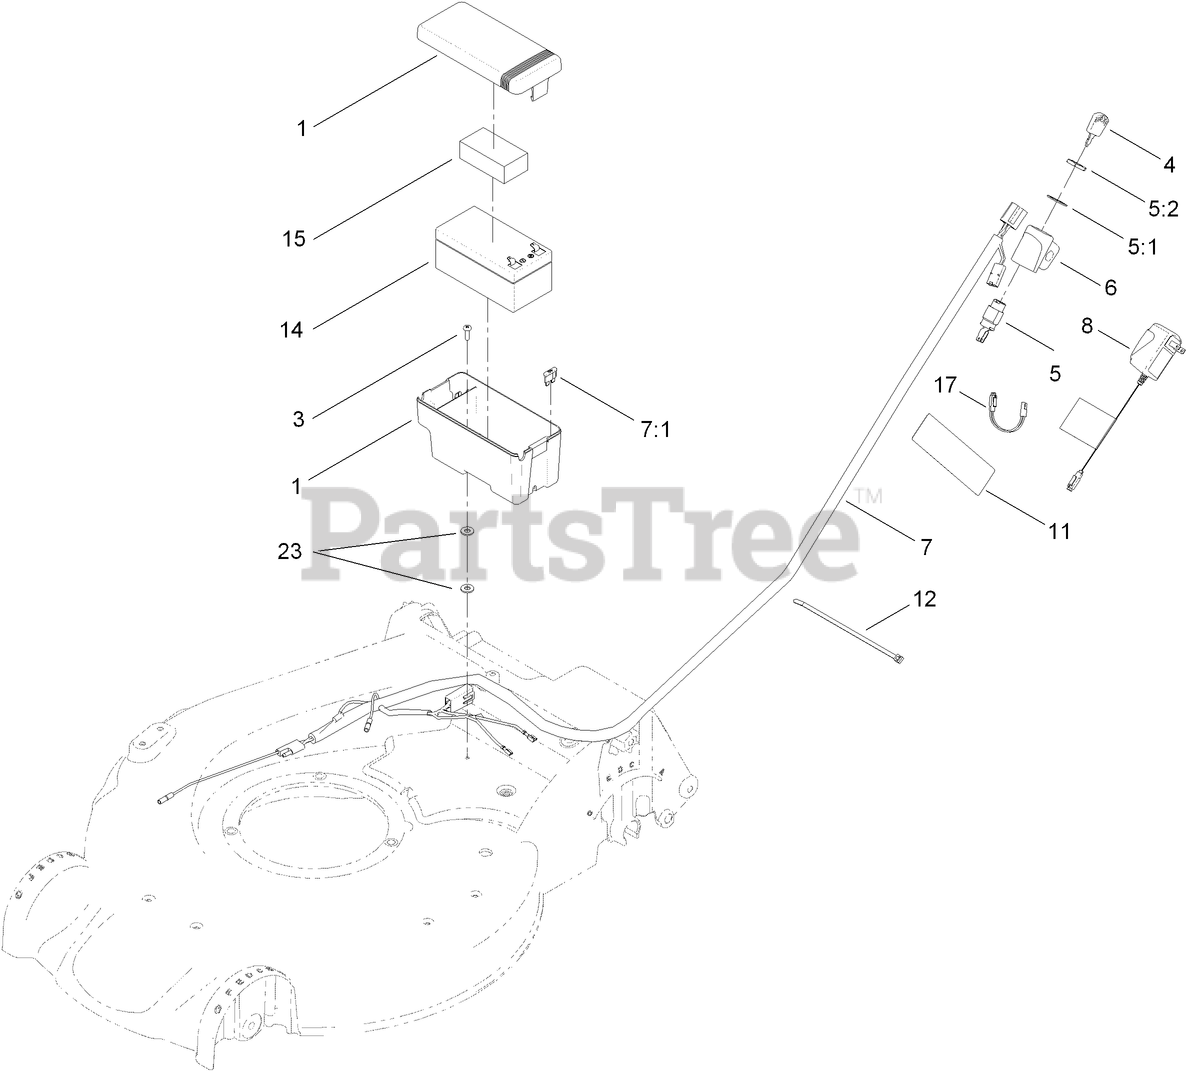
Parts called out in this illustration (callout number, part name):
1	BATTERY BOX ASM
5	STARTER SWITCH ASM
5:1	WASHER-LOCK
5:2	NUT-HH
6	MOUNT-SWITCH
7	HARNESS-WIRE
7:1	FUSE-40 AMP
8	CHARGER-EUROPEAN, 12V DC
11	DECAL-WARNING
12	TIE-CABLE
14	BATTERY-WET
15	FOAM-BATTERY, TOP
17	ADAPTER-CHARGER
23	WASHER-FLAT
